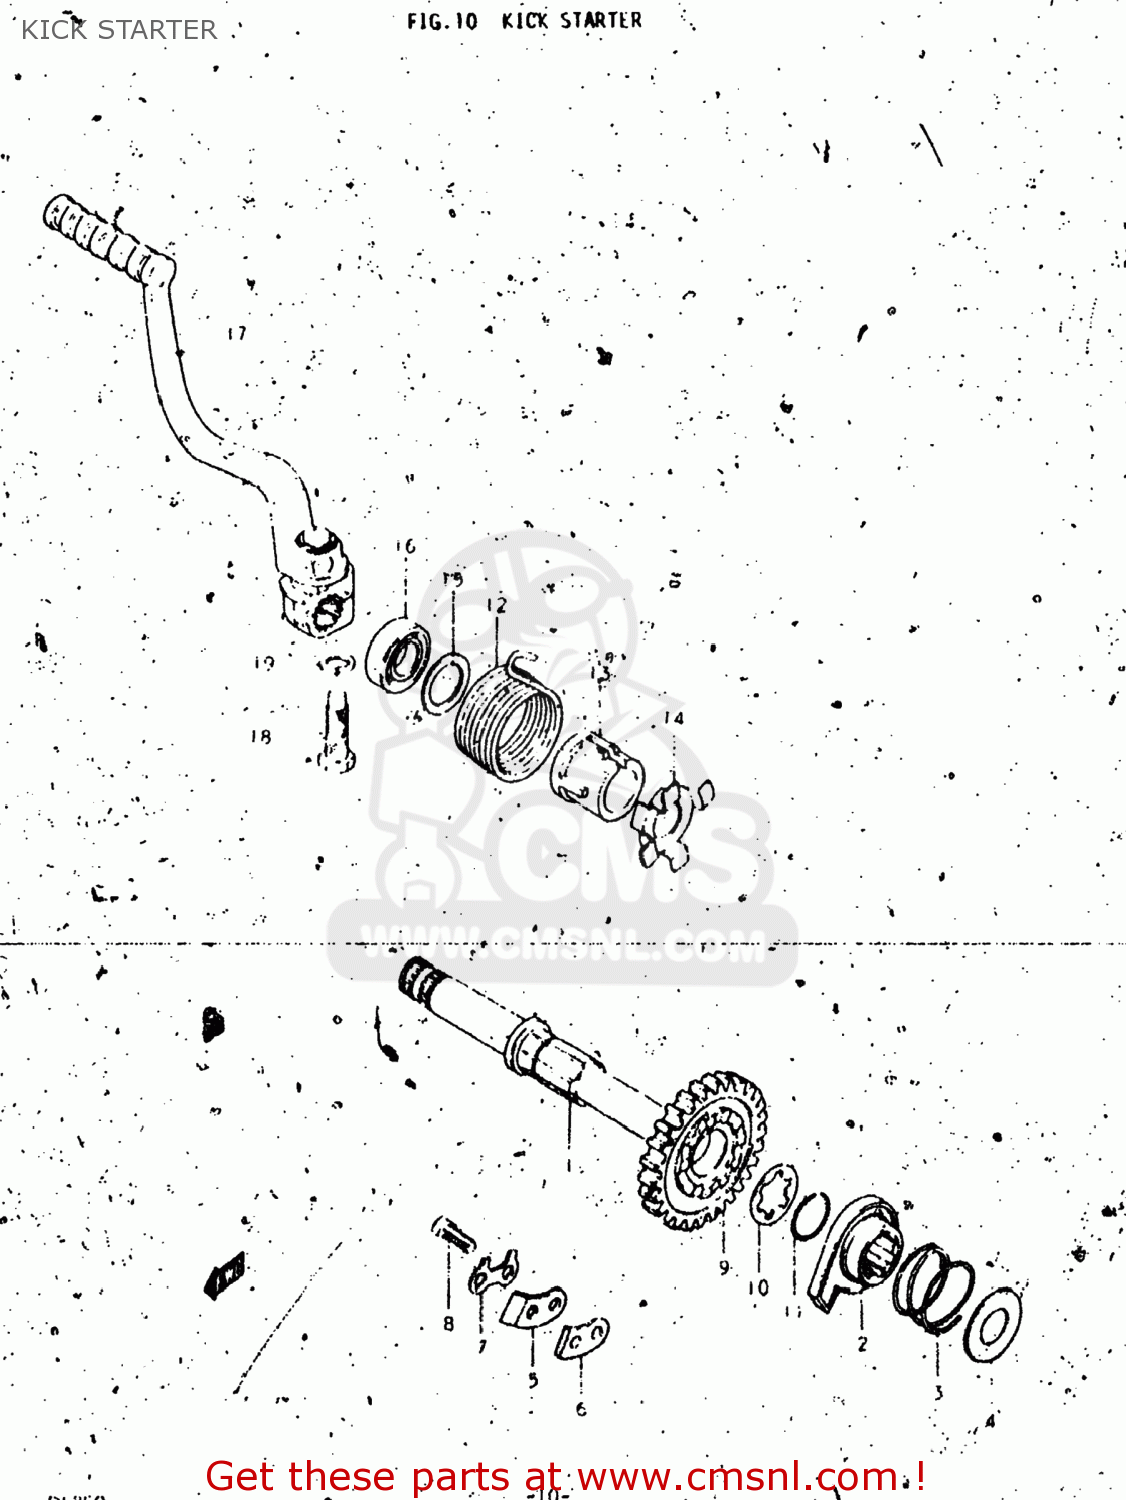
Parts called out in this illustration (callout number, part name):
1	SHAFT,KICK STARTER
2	STARTER,KICK
3	SPRING
4	WASHER
5	GUIDE,KICK STARTER
6	STOPPER,KICK STARTER
7	WASHER
8	BOLT
9	GEAR,KICK STARTER DRIVE
10	WASHER,LOCK
11	CIRCLIP
12	SPRING
13	GUIDE,KICK SHAFT SPRING
14	HOLDER,KICK SHAFT SPRING
15	WASHER
16	OIL SEAL
17	LEVER ASSEMBLY,KICK STARTER
18	BOLT(10X37.5)
19	LOCK WASHER
